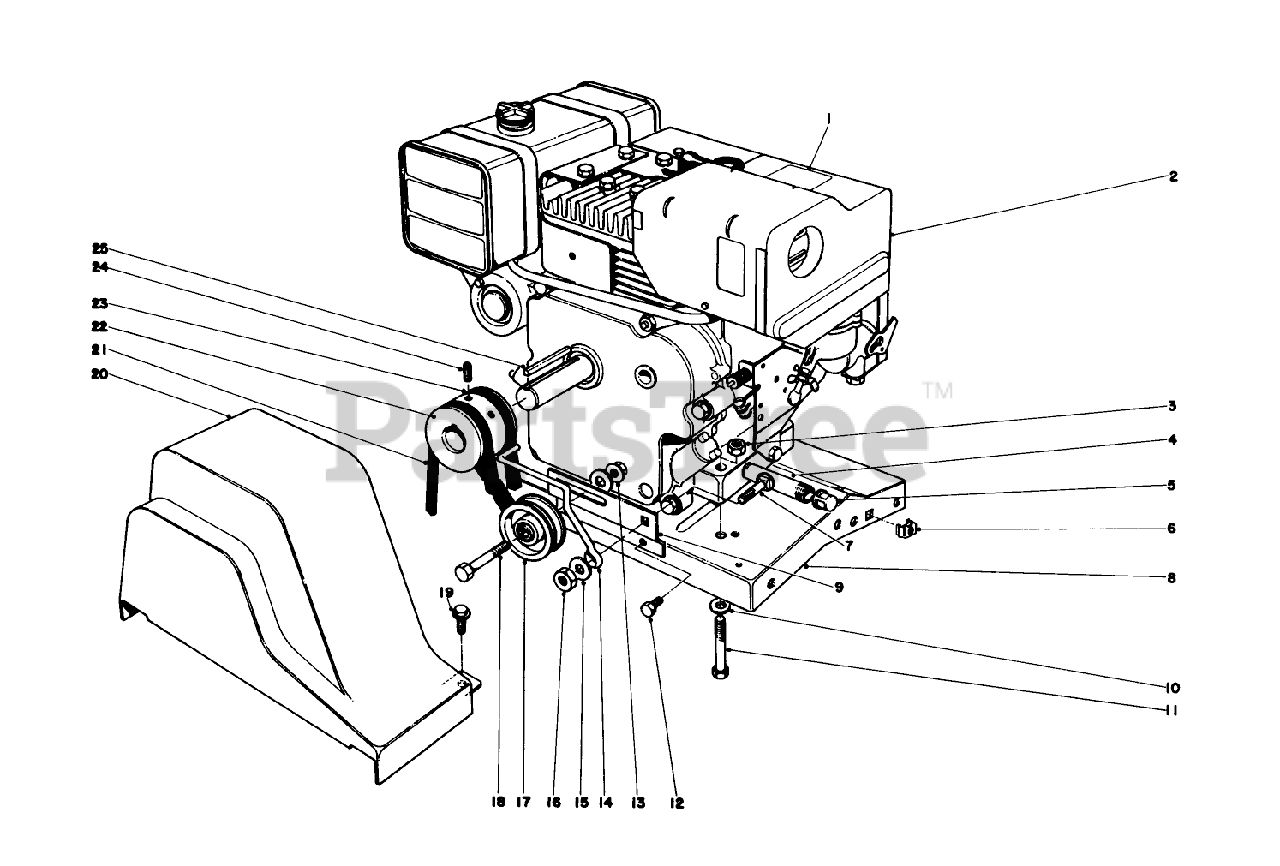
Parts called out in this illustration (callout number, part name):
1	Decal Instruction
2	Engine
3	NUT-LOCK, CONE
4	NIPPLE-PIPE
5	CAP-PIPE
6	Retained Nut
7	SCREW-CARR
8	Engine Base
9	Belt Idler Bracket
10	WASHER-PLAIN
11	SCREW-HH
12	SCREW-HH, TAP
13	NUT-HHF, WHIZ
14	BELT GUIDE
15	WASHER-FLAT
16	NUT-HEX
17	Idler Pulley
18	SCREW-HH
19	SCREW-HWH
20	BELT GUARD
21	V-Belt
22	Pulley
23	V-Belt
24	Screw-Set
